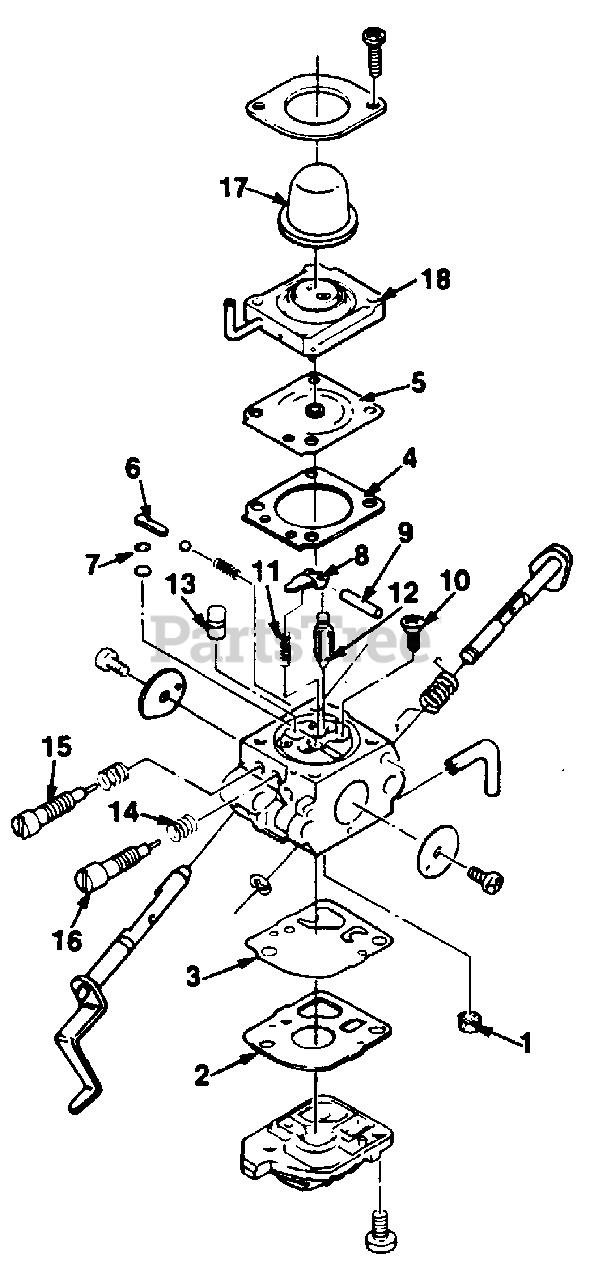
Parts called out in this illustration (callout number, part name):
1	REPAIR KIT (1-16)
2	REPAIR KIT (1-16)
3	REPAIR KIT (1-16)
4	REPAIR KIT (1-16)
5	REPAIR KIT (1-16)
6	REPAIR KIT (1-16)
7	REPAIR KIT (1-16)
8	REPAIR KIT (1-16)
9	REPAIR KIT (1-16)
10	REPAIR KIT (1-16)
11	REPAIR KIT (1-16)
12	REPAIR KIT (1-16)
13	REPAIR KIT (1-16)
14	REPAIR KIT (1-16)
15	REPAIR KIT (1-16)
16	REPAIR KIT (1-16)
17	Primer Bulb (17)
18	Primer Base (18)
